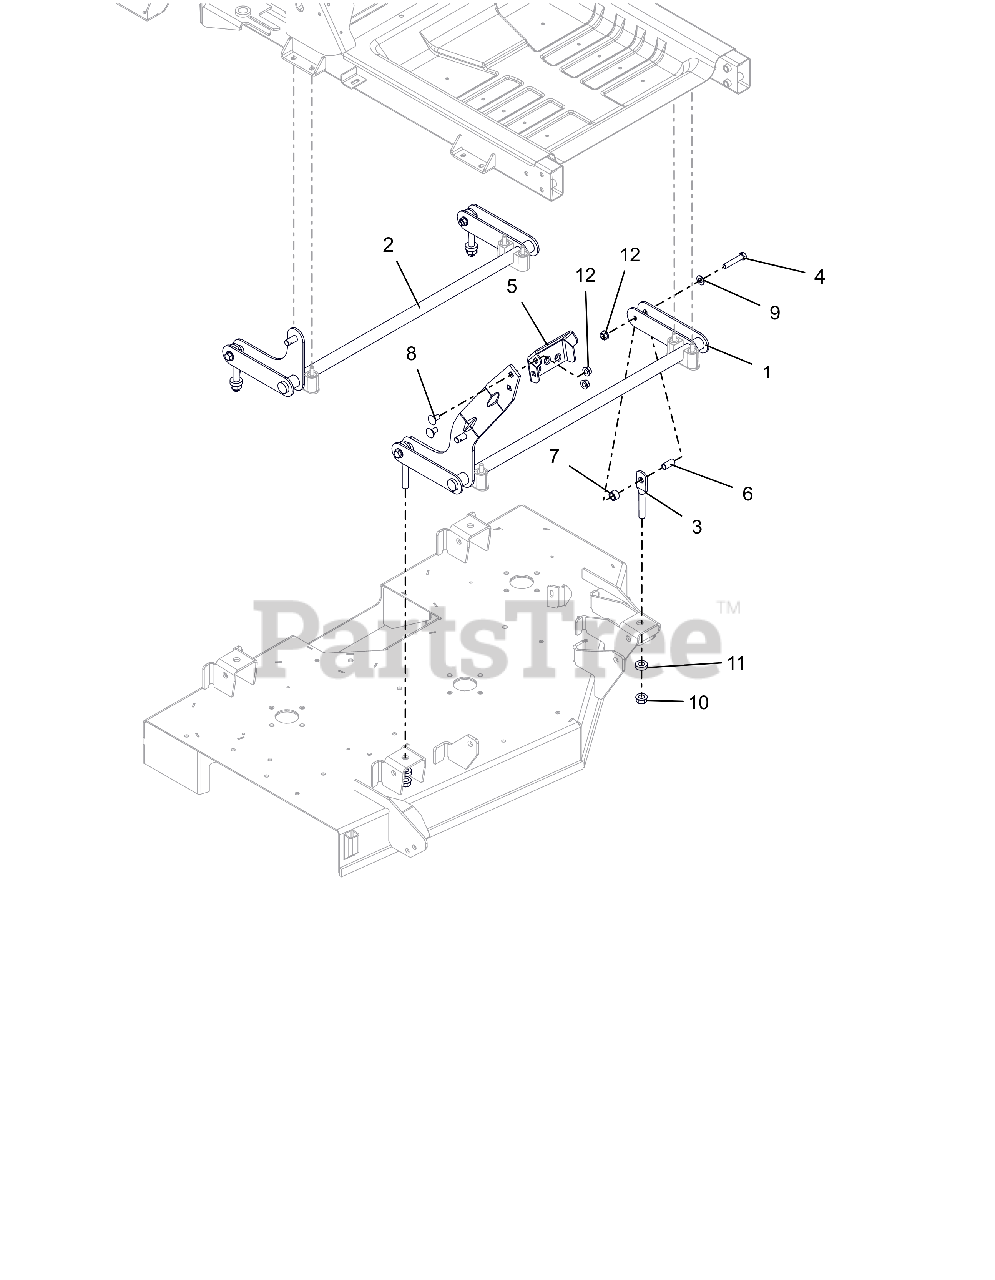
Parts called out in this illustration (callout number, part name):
1	WLDMT, FRONT DECK LIFT PIVOT
2	WLDMT, REAR DECK PIVOT
3	LINK, DECK (HOLE-SHORT)
4	BLT, HEX .38-16X2.00 G8 ZCC
5	PEDAL, DECK LIFT (BOLT ON)
6	BSHG-SLV .385X.500X1.045
7	BSHG-SLV .510X.751X.475
8	BLT,RHSN .38-16X.75 G5 BFP
9	WSHR,FLT .406X.812X.065 ZCC
10	NUT-LK-CTR-FLG .500-13 GG ZCC
11	WASHER, RUBBER
12	NUT-LK-CTR-FLG .375-16 GF ZCC
